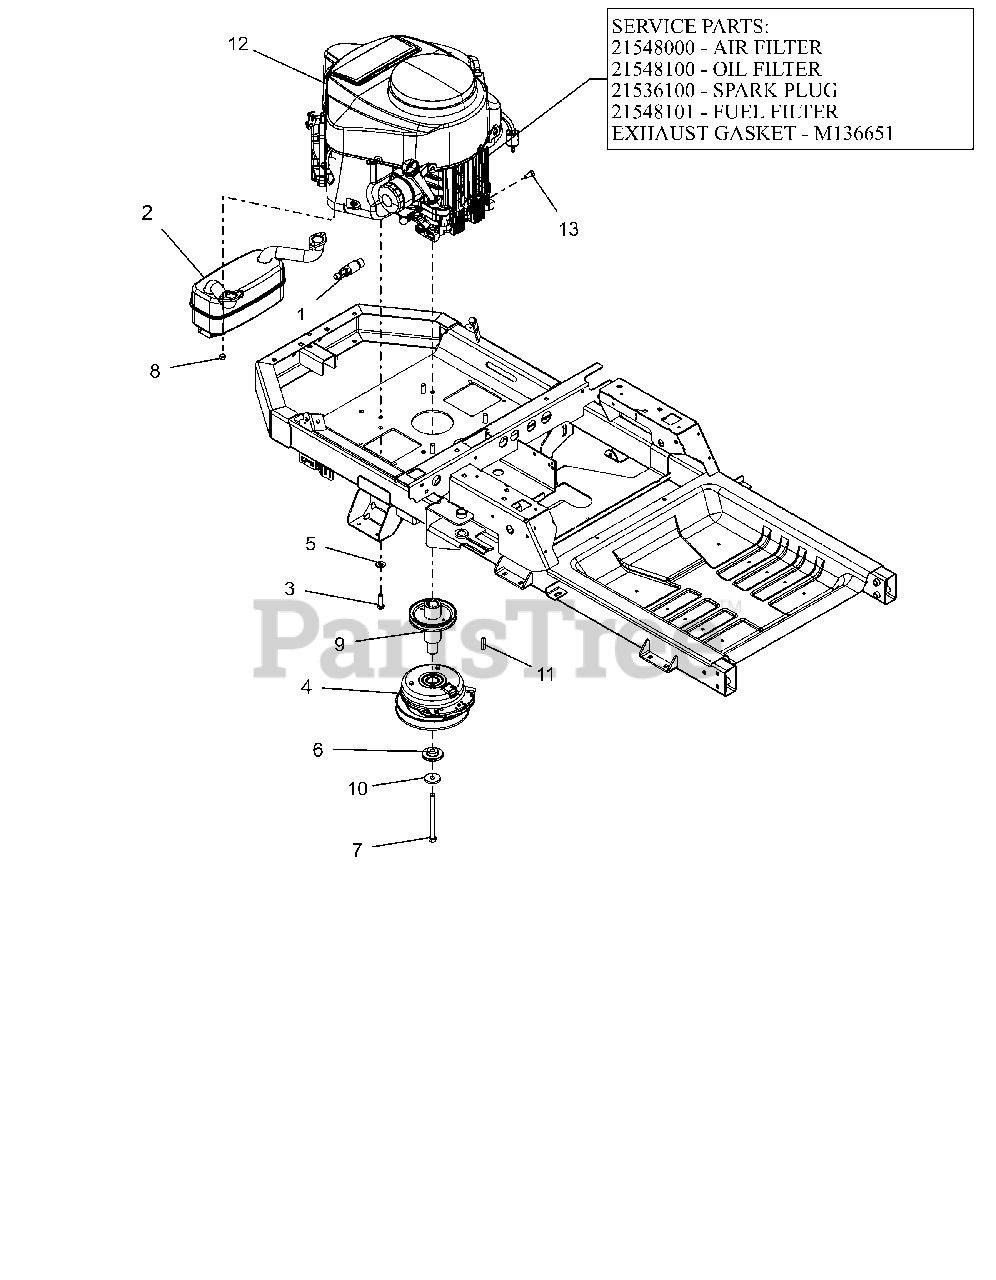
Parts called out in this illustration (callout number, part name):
1	DRAIN, OIL M20X2.5
2	MUFFLER, KAWASAKI
3	BLT-HEX.38-16X1.25 G5YZ NYTORQ
4	CLUTCH,105FTLB MONOPOLE 6.83"
5	WASHER, 3/8" SPRING DISC
6	BSHG-FLG .469X1.06X.574X2.0
7	BLT-HEX.438-20X5 GR8 YZ NYTORQ
8	NUT-LK-TOP M8-1.25 YWZC
9	WLDMT, DRIVE SHEAVE (LG XL)CZC
10	WASHER, 7/16" SPRING DISK
11	KEY-SQ .25 X 1.25 X .25 SAE
12	ENGINE, KAWASAKI FR651V 21.5HP
12	AIR FILTER, KAWASAKI FR
12	OIL FILTER, KAWASAKI FR
12	PLUG, SPARK
12	FUEL FILTER-KAWASAKI FR
12	GASKET, MUFFLER #
13	BLT, HEX M8-1.25X20 G8.8 ZCC
